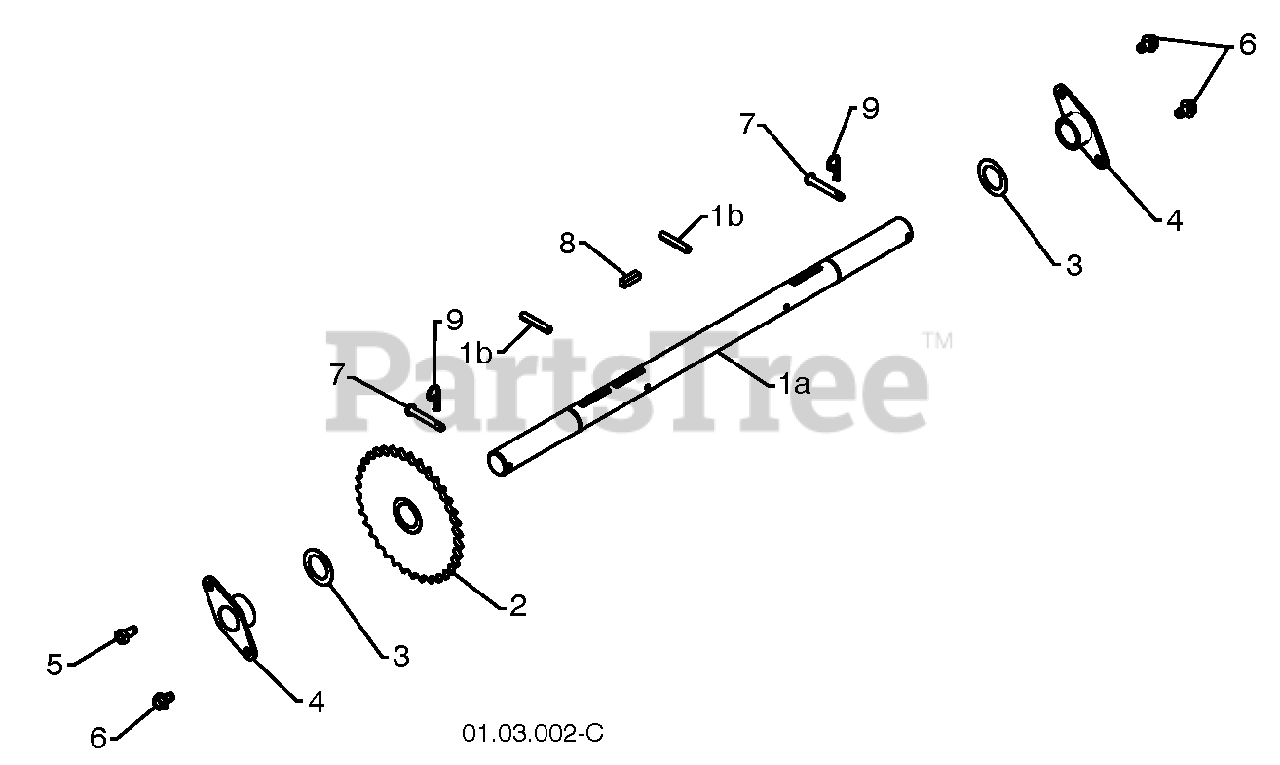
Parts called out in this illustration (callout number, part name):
2	SPROCKET.WELDMENT.AXLE.1.00
3	WASHER 1.00
4	BEARING, AXLE
6	SCREW LT
7	RIVET
8	KEY, SQUARE 1/4 X .875
9	RETAINER M
